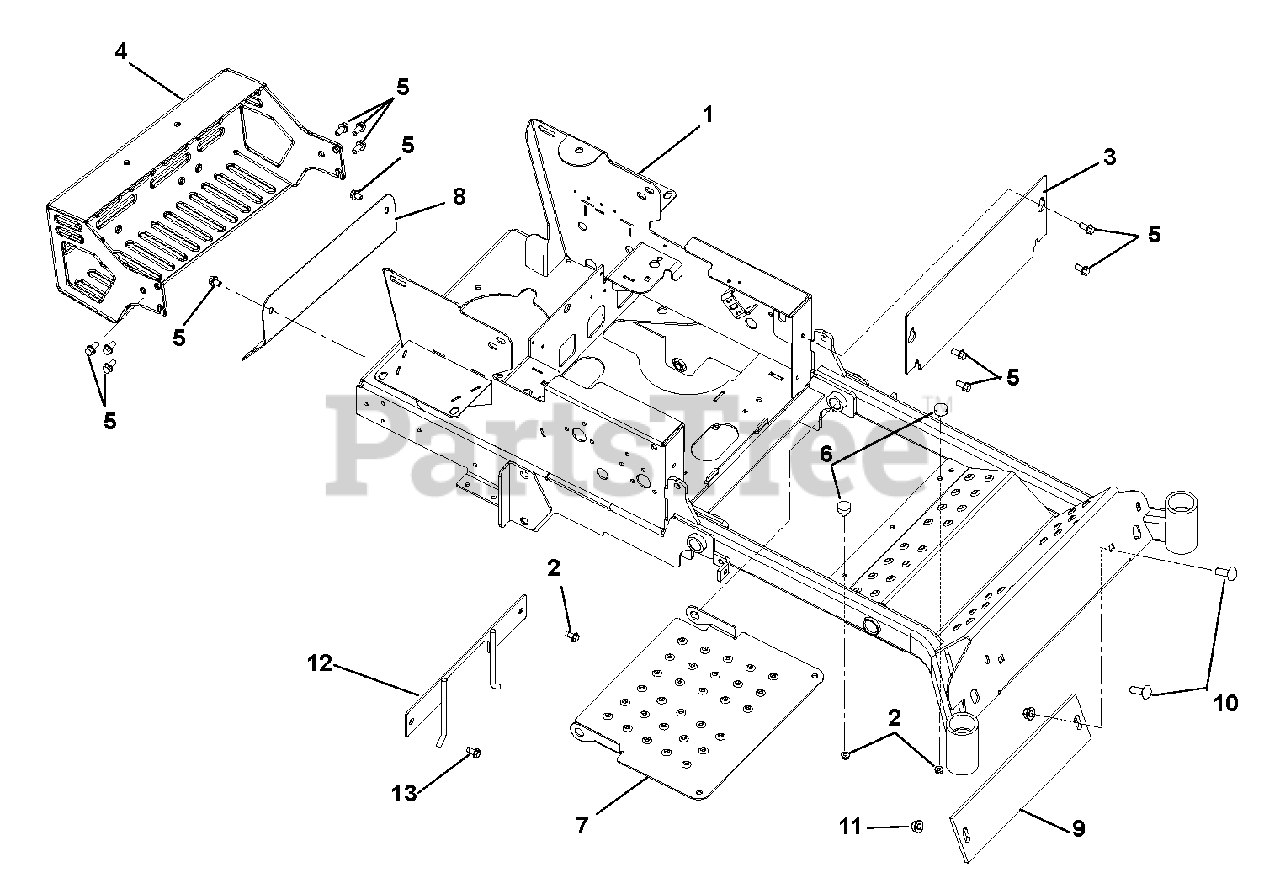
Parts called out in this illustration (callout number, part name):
1	Weldment, 44" – 48" HD Frame (991090, 082, 098, 099)
1	Weldment, 52" – 60" HD Frame (991083, 084, 091, 100, 101)
2	Nut, Spin Lock Flange .312-18
3	Kick Plate
4	Bumper, Gravely HD
5	Screw, Tapping .38-16 x .75 Hex Washer Head
6	Bumper, Rubber
7	Panel, Inspection
8	Bracket, Heat Shield — Muffler
9	Counterweight CZ Front (991090, 082, 098, 099) (Serial No. 020000 – 021999)
10	Bolt, Round Head Square Neck .50-13 x 2.25 Grade 5 (Serial No. 020000 – 021999)
11	Nut .50-13 Nyloc Flange (Serial No. 020000 – 021999)
12	Weldment, PTO Belt Finger
13	Screw, Tapping .38-16 x .75 Hex Washer Head Thread
